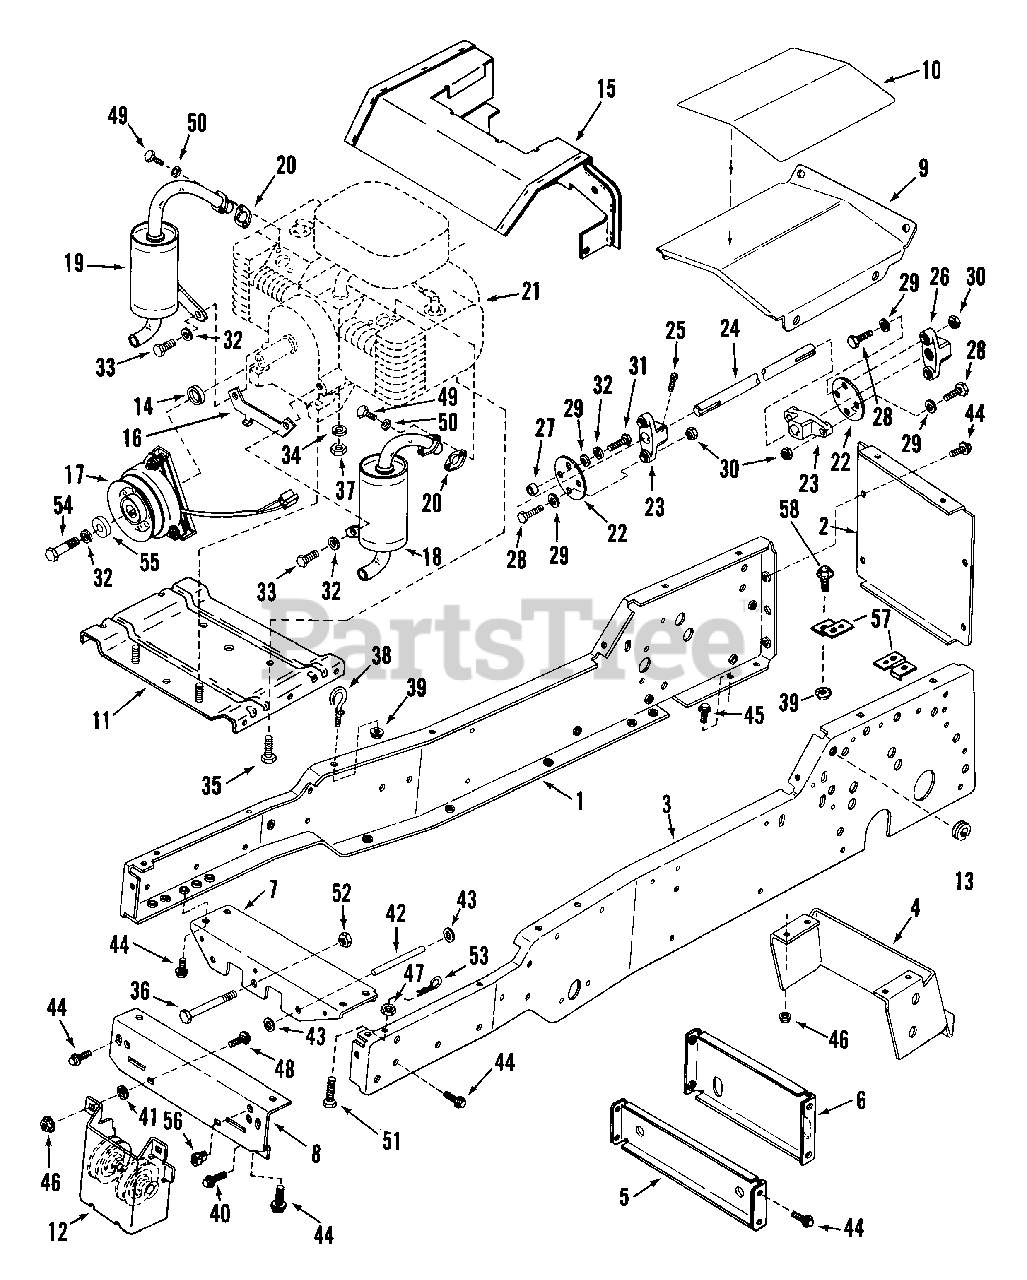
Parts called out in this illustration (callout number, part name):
1	CHANNEL, R.H. Frame (NLA)
1	CHANNEL, R.H. Frame '85 (NLA)
2	PLATE, Rear Cover
2	PLATE, Rear Cover '85
3	CHANNEL, L.H. Frame (NLA)
3	CHANNEL, L.H. Frame '85 (NLA)
4	DRAWBAR
5	BRACE, Forward
6	BRACE, Rear Cross (NLA)
7	CHANNEL, Front Axle Support
8	A'SSY, Front Plate
9	COVER, Console
10	DECAL, Console Cover
11	BASE, Engine (NLA)
12	ASSEMBLY, Mule Drive
13	GROMMET, Split
14	SPACER, 1" x 1 3/8 x .30" (PM)
15	ASS'Y, Heat Shield
16	BRACKET, Clutch Retainer
17	KIT, Electric Clutch
18	MUFFLER, B&S 16HP Engine LH
19	MUFFLER, B&S 12HP Engine RH
20	GASKET, Exhaust
22	DISC, Flex Coupling
23	HUB, Flex Coupling
24	SHAFT, Drive (22.62 x.75)
25	SET-SCREW, 5/16-18 x 1/2"
26	HUB, Flexible Coupling (Threaded center)
27	SPACER, Flexible Coupling
28	SCREW, 3/8-16 x 1" H HC
29	WASHER, 3/8" Flat
30	NUT, 3/8-16 Hex Center Lock
31	SCREW, 3/8-16 x 1-1/4" Hex Head Cap, Grade 5
32	WASHER, 3/8 Split Lock
33	SCREW, 3/8-16 x 7/8" Hex Head Cap
34	WASHER, 5/16 Split Lock
35	SCREW, 3/8-16 x 1" Hex Head Self-Tap
36	SCREW, 1/2-20 x 4" Hex Head Cap, Grade 5
37	NUT, 5/16-18 Hex
38	HOOK, Hood Latch
39	NUT, 5/16-18 Hex Flange Lock
40	SCREW, 1/4-20 x 5/8" Hex Washer Self-Tap
41	RETAINER, 3/8 Bolt
42	STOP, Axle
43	RETAINER, 3/8 Shaft
44	SCREW, 5/16-18 x 5/8" Hex Washer Self-Tap
45	BOLT, 3/8-16 x 3/4" Hex Flange Lock
46	NUT, 3/8-16 Hex FL Lock
47	NUT, 1/4-20 Hex Top Lock Jam
48	BOLT, 3/8-16 x 3/4" Square Neck Carriage
49	SCREW, 1/4-20 x 5/8" Hex Hex Head Cap
50	WASHER, 1/4 Split Lock
51	BOLT, 1/4-20 Hex Head Drilled
52	NUT, 1/2-20 Hex Nyloc
53	PIN, 1/4 Hair
54	SCREW, 3/8-24 x 1-5/8" Hex Cap, Grade 5
55	WASHER, Pull Bar
56	RELIEF, Strain
57	BRACKET, Rear Fender Mounting (NLA)
58	BOLT, 5/16-18 x 1" Hex Flange Lock Bolt
